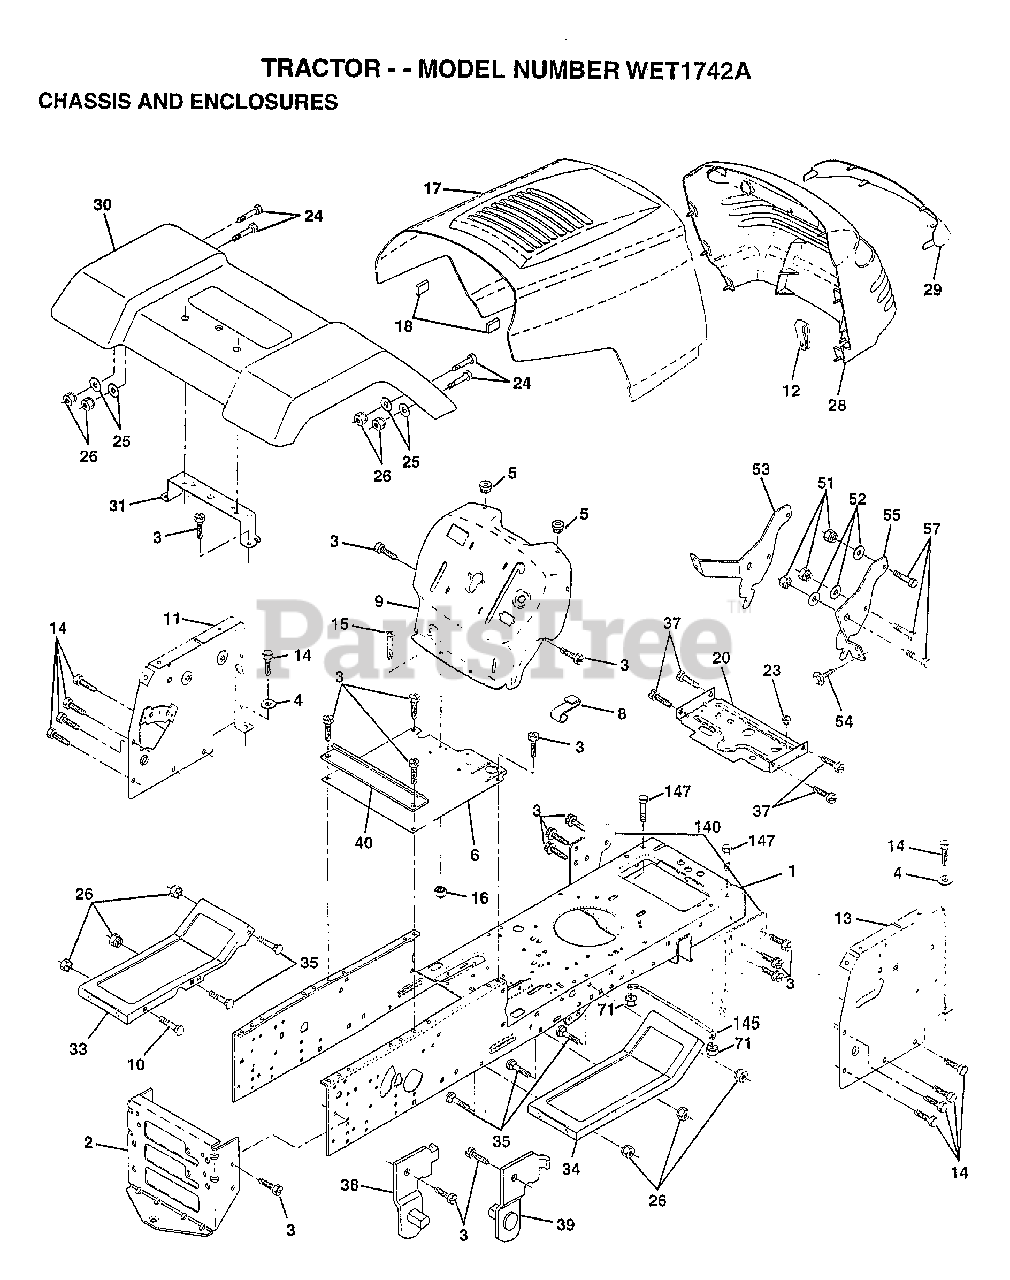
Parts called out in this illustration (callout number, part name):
1	CHASSIS ASM
3	SCREW
4	WASHER
5	BUMPER-HOOD/DASH
6	SADDLE
8	"CLIP,INSULATOR"
9	DASH.SILKSCREENED
11	"PANEL-DASH,LH"
12	CLIP.TINNERMAN
14	SCREW LT
15	SCREW
20	"PLATE-MTG,BATT/FU"
24	BOLT
25	WASHER
26	NUT
28	GRILLE-MS428
29	LENS GRILLE
30	FENDER
31	BRACKET SUPT FEND
33	FOOTREST.LH.LT/GT
34	FOOTREST.RH.LT/GT
35	BOLT
37	SCREW LT
38	BRACKET ASM LH
39	BRACKET ASM RH
40	SPACER FENDER LT
51	NUT
52	WASHER
53	BRACKET.GRILLE.LH
55	BRACKET.GRILLE.RH
140	BRKT SUSPENSION
145	"ROD POVOT,CHASSIS"
147	BOLT LT
